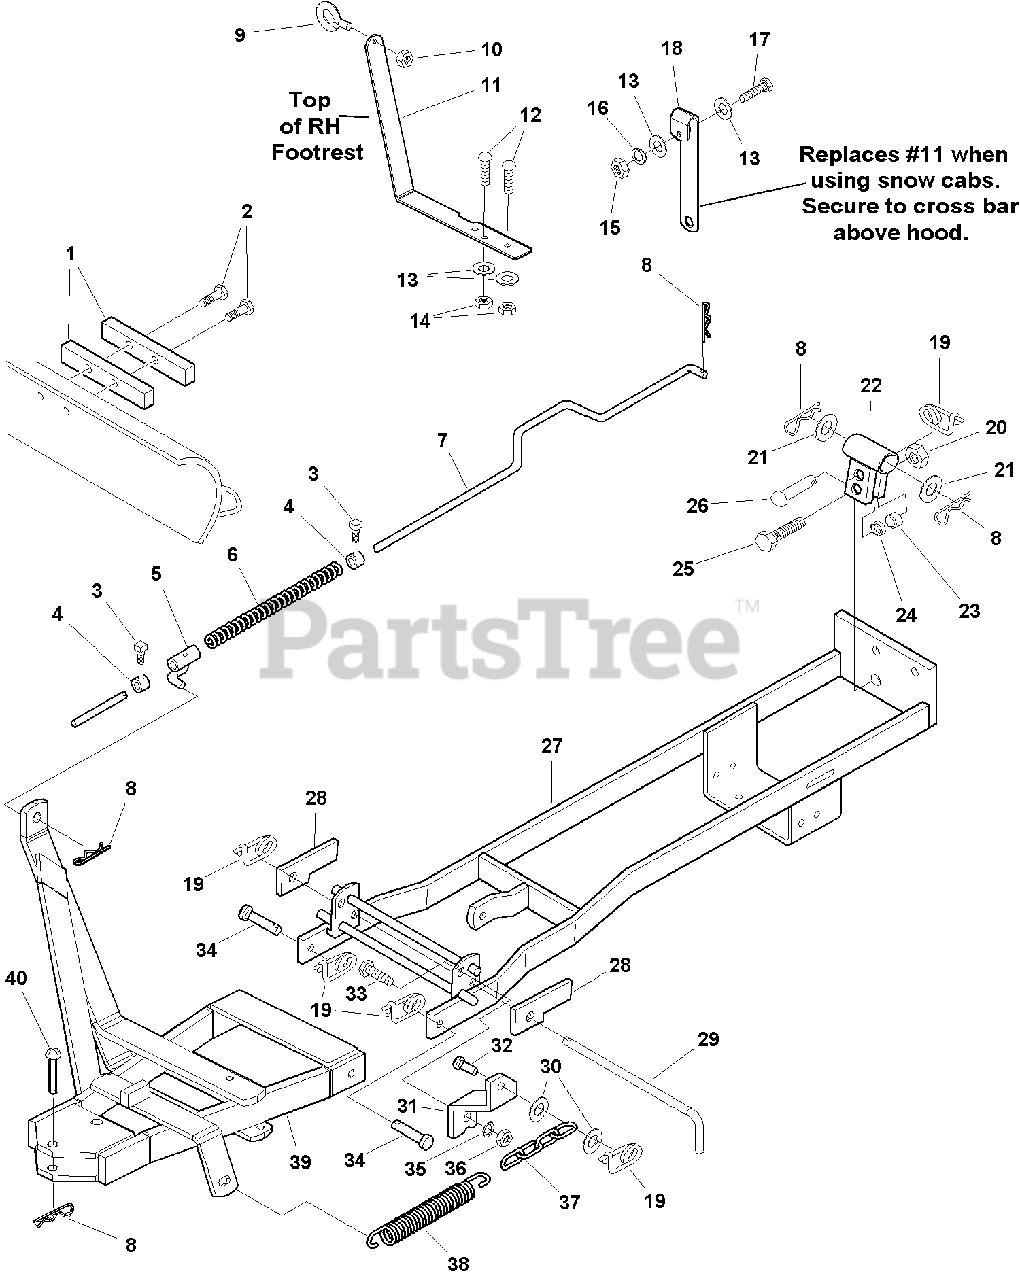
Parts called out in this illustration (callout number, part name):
1	BAR
2	CAPSCREW, Taptite, 5/16-18 x 1
3	SCREW, Set, 5/16-18 x 1/2
4	COLLAR
5	GUIDE ASSEMBLY
10	LOCKNUT, Hex, 1/4-20
11	BRACKET, Control Rod
12	CARRIAGE BOLT, 5/16-18 x 1-1/4
13	WASHER, 5/16
14	NUT, Centerlock, 5/16-18
15	NUT, Hex, 5/16-18
16	LOCKWASHER, 5/16
17	CAPSCREW, Hex Head, 5/16-18 x 1-1/2
18	BRACKET, Control Rod (Used With Snow Cab)
19	RETAINER, Pin
20	NUT, Whizlock, 3/8-16
21	WASHER
22	SUPPORT ASSEMBLY
25	CAPSCREW, Hex Head, 5/16-18 x 2
26	PIN, Round Head, Drilled
27	PUSH BAR ASSEMBLY
28	STOP
30	WASHER, 5/16
32	PIN
33	CAPSCREW, Hex Head, 1/2-13 x 1-1/4
35	LOCKWASHER, 1/2
36	NUT, Hex, 1/2-13
39	PUSH BAR ASSEMBLY
